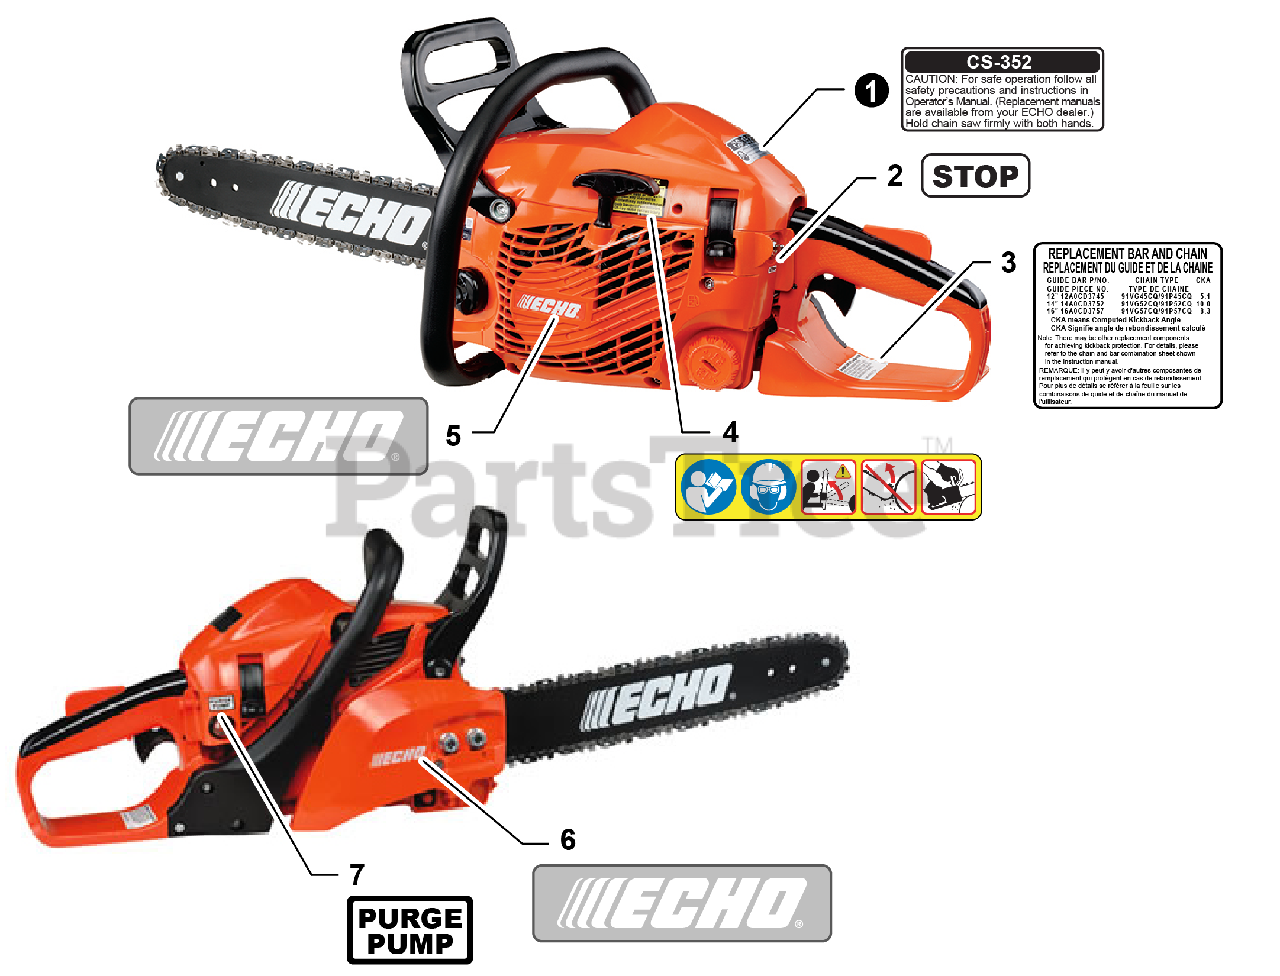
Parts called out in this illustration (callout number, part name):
1	LABEL, CS-352 CANADA
2	LABEL, STOP
3	LABEL, BAR & CHAIN
4	LABEL, CAUTION
5	LABEL, ECHO
6	LABEL, ECHO
7	LABEL, PURGE PUMP
